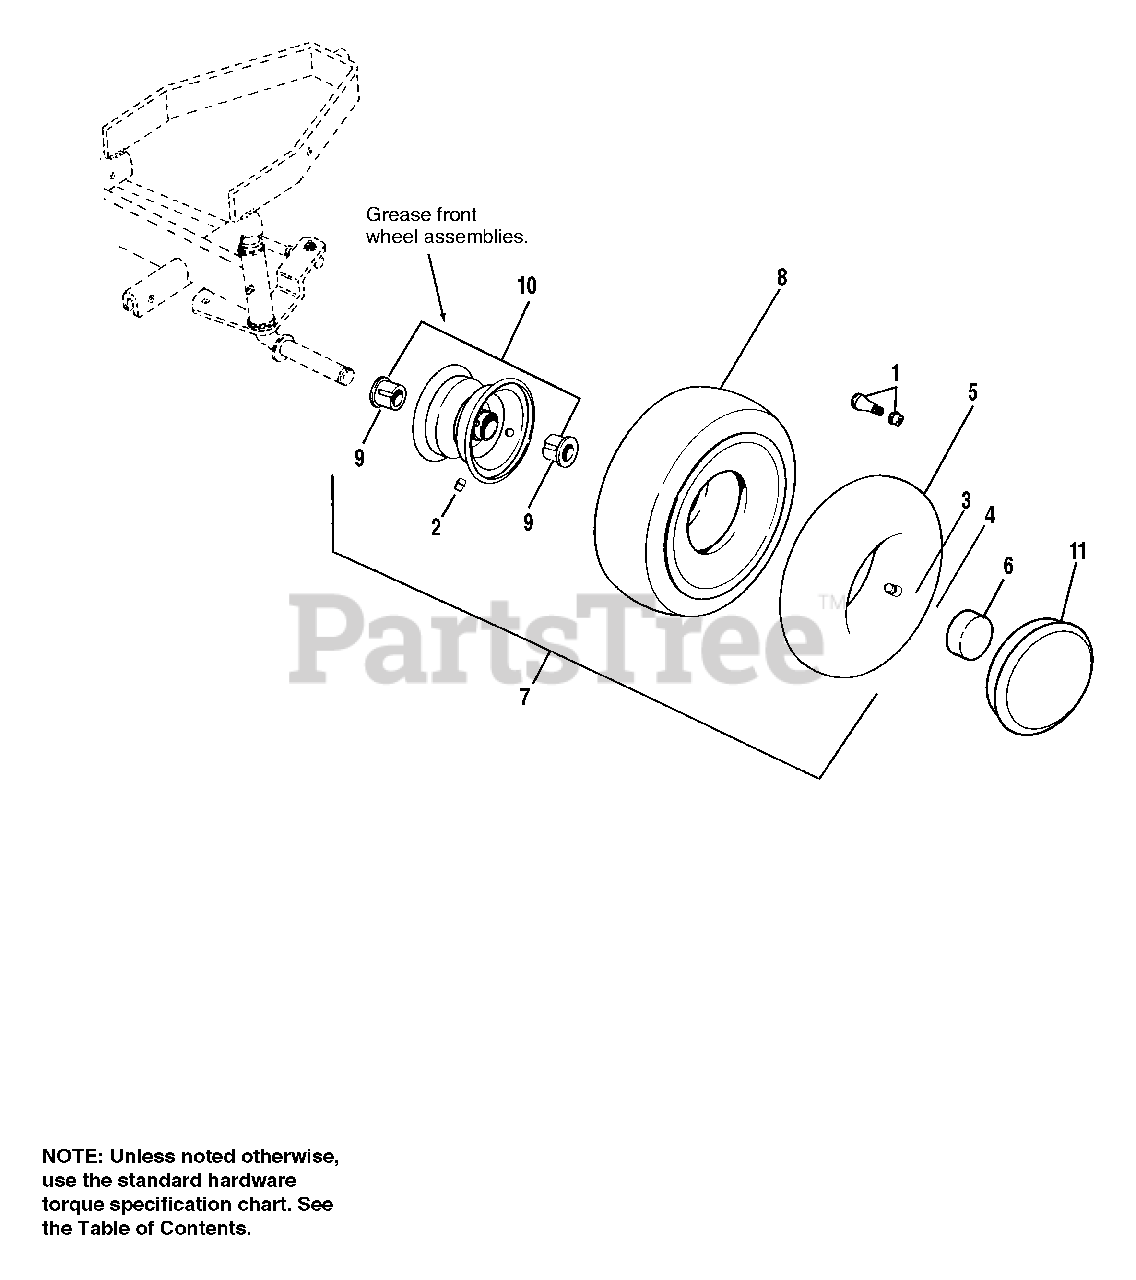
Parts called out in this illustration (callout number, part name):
1	VALVE STEM & CAP
2	FITTING, Grease
3	WASHER, 3/4
4	KLIP RING, 3/4
5	TUBE, Front Wheel, 4.10/3.50-6
6	HUB CAP
7	FRONT WHEEL & TIRE ASSY., Metallic Gray, 15 x 6.00-6
8	TIRE, Front Wheel, 15 x 6.00-6
9	BEARING
10	FRONT WHEEL ASSY., Metallic Gray
11	HUB CAP, 6"
